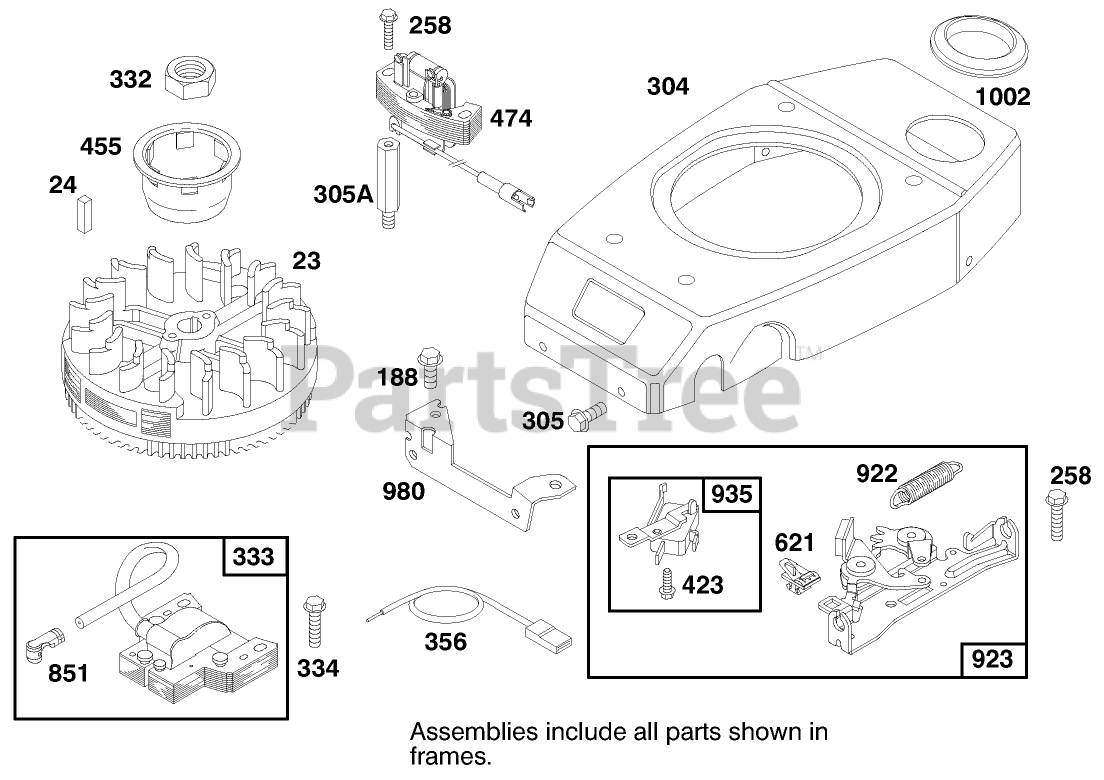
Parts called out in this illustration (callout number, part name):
23	FLYWHEEL - MAGNETO
24	KEY - FLYWHEEL
305	SCREW - HEX HEAD
332	NUT - HEXAGON
334	SCREW - SEM
356	WIRE - GROUND
455	CUP - STARTER
621	STOP SWITCH
980	BRACKET-BLOWER HSG
